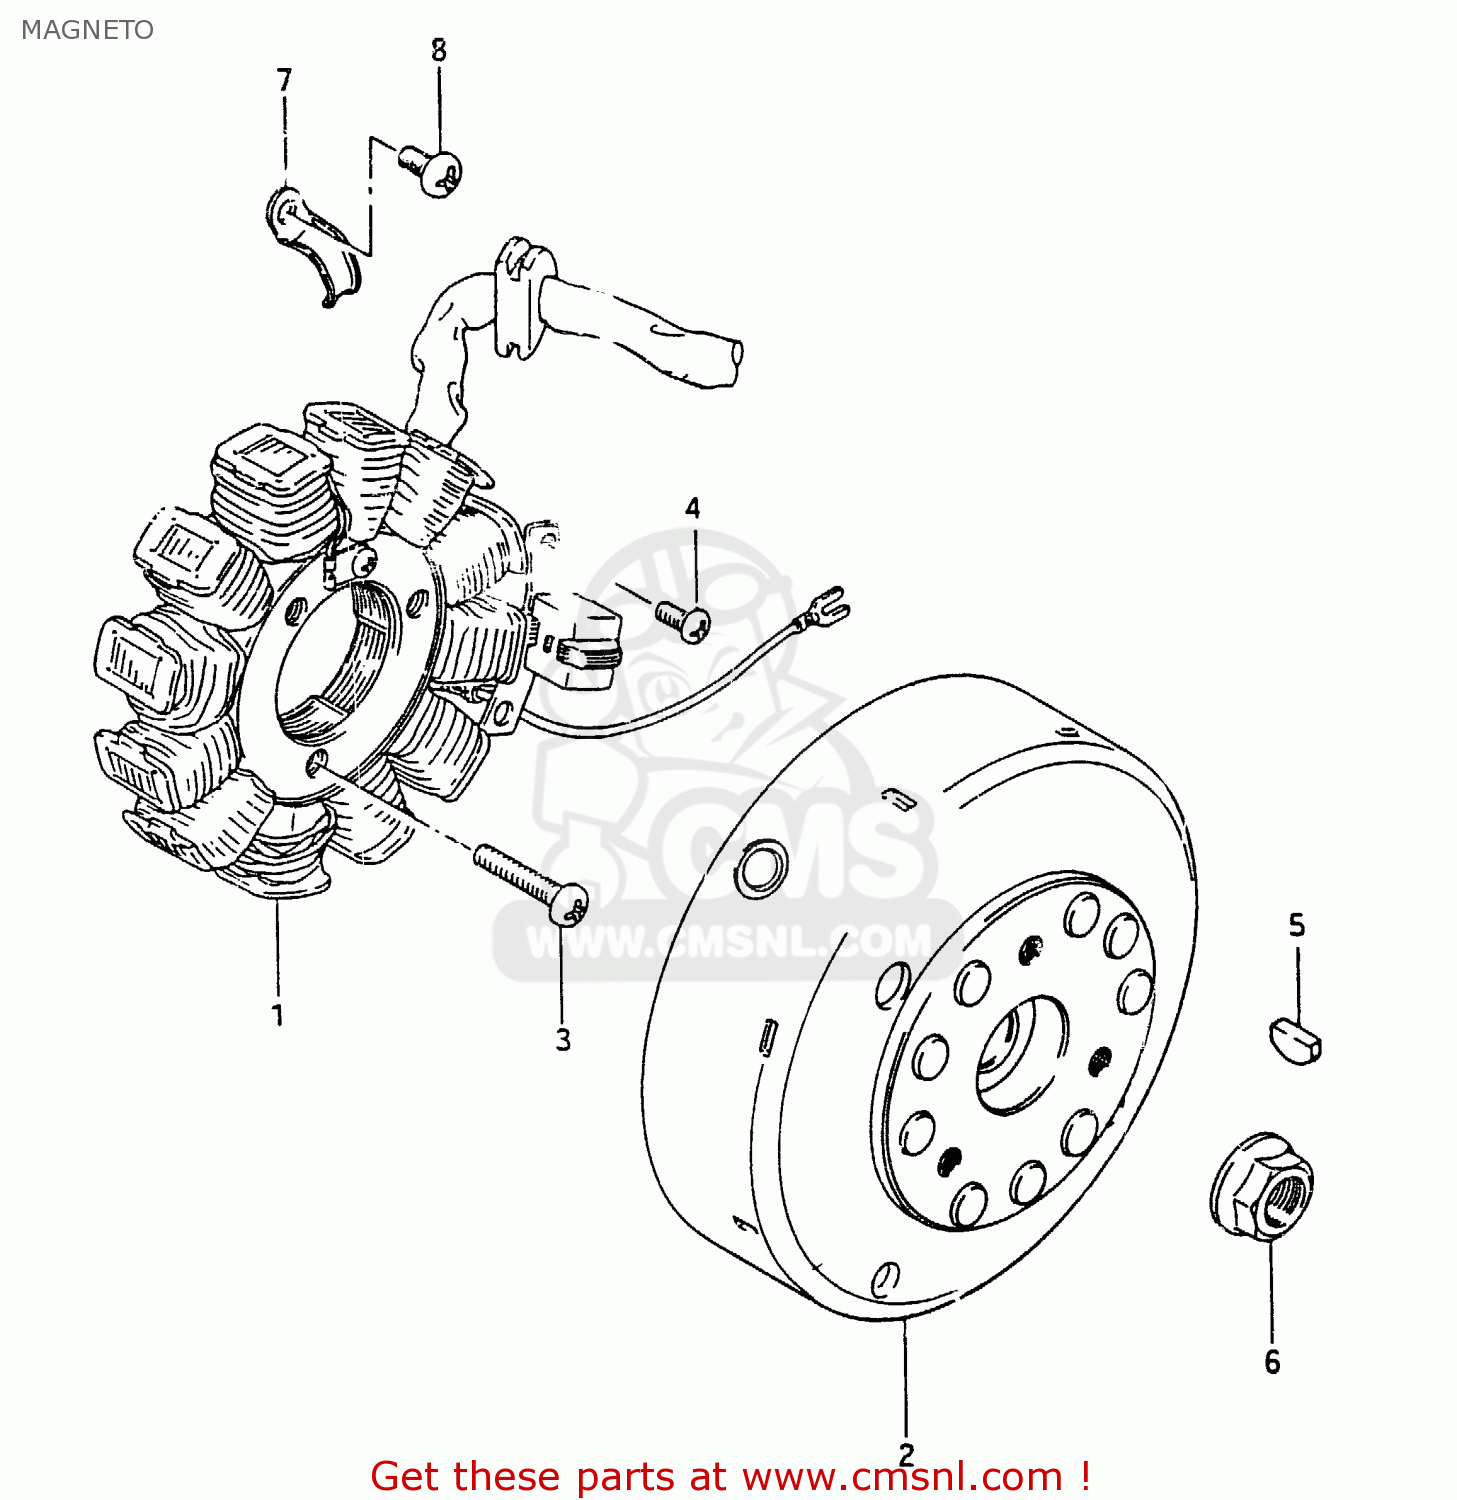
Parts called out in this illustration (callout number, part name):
1	STATOR ASSY
2	ROTOR, FLYWHEEL
3	SCREW
4	SCREW
5	KEY
6	NUT 12MM
7	CLAMP
8	SCREW
